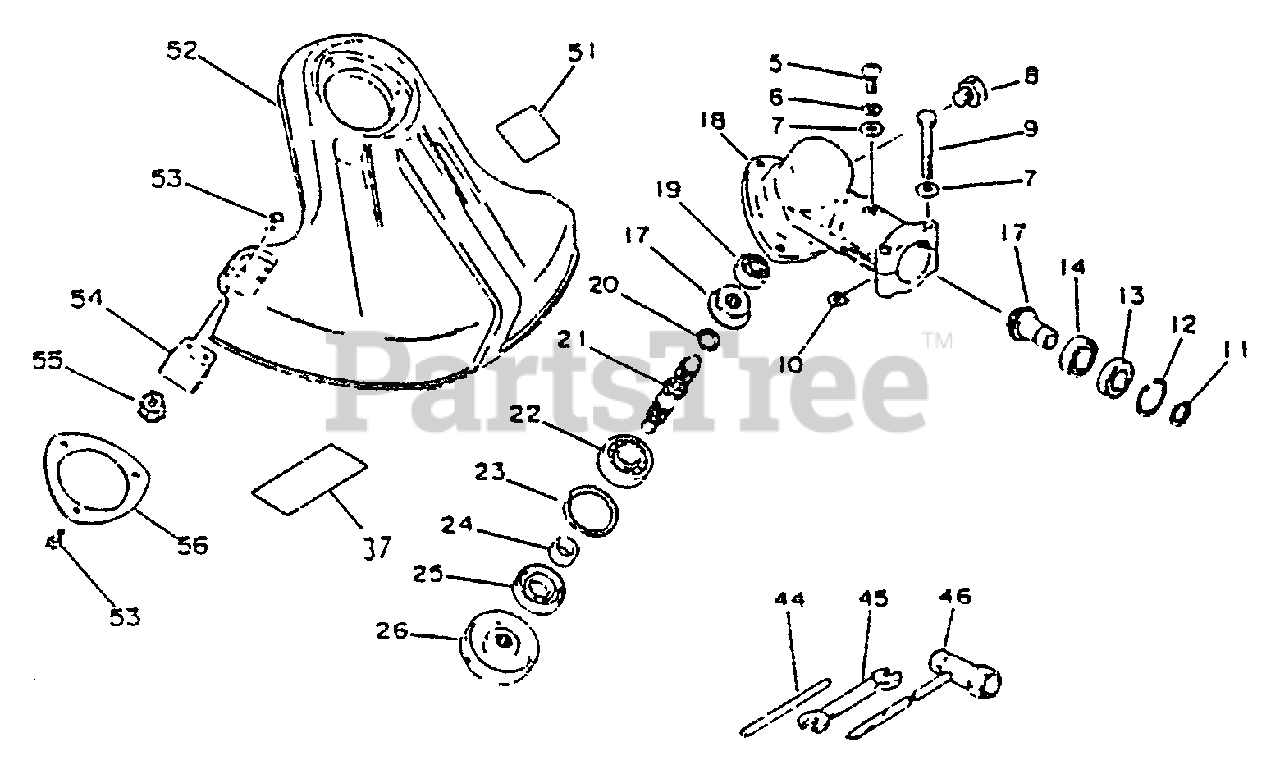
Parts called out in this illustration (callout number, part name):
5	SCREW - 5X10
6	LOCKWASHER - 5
7	WASHER - 5
8	BOLT - 8X8
9	BOLT - 5X35
11	RING, RETAINING - 12
12	RING, RETAINING - 22
13	BEARING, BALL - 6900Z
14	BEARING, BALL - 6900
17	GEAR SET - BEVEL
18	CASE, GEAR
19	BEARING, BALL - 609
20	RING, RETAINING - 10
21	GEAR - SHAFT
22	BEARING, BALL - 6201
23	RING, RETAINING - 32
25	SEAL, OIL
26	ADAPTOR, BLADE - UPPER
37	LABEL - ECHO
44	LOCKING TOOL
45	SPANNER - 8X10mm
46	T-WRENCH - 17X19mm
51	LABEL - CAUTION
52	SHIELD, DEBRIS
53	SCREW - 5X16
54	KNIFE, TRIMMER LINE
56	PLATE, SHIELD
